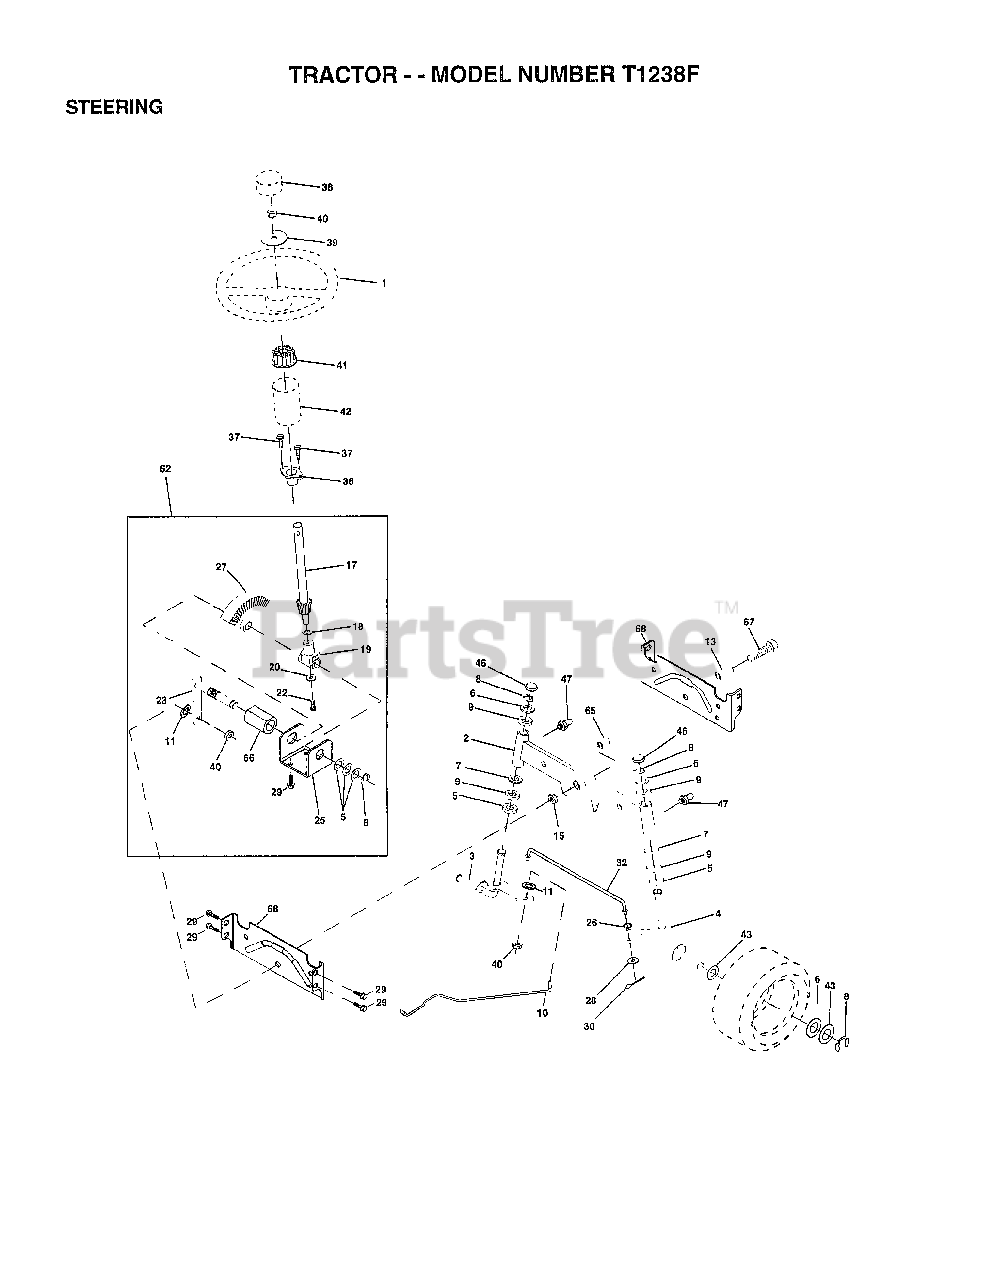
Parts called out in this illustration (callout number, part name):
2	AXLE ASM
3	SPINDLE.ASM.LH
4	"SPINDLE ASM,RH"
5	WASHER .T
6	WASHER
7	WASHER
8	RING
9	COL. SRTG. BEAR.
10	DRAGLINK-STAMPED
11	LOCKWASHER
13	BEARING AXLE
15	"NUT-LOC,FLANGE LT"
17	SHAFT ASSM STEERN
18	THRUST WASHER
19	SUPPORT.SHAFT
22	SCREW HEX SOC1/4-
25	BRKT-STEERING
26	BUSHING.DRAGLINK
27	GEAR SECTOR
28	WASHER
29	SCREW
30	COTTER PIN
32	TIE ROD
36	BUSHING.STEERING
37	"SCREW-TT,10-32 FL"
38	ST WHL INSERT CAP
39	WASHER T
40	GRIPCO NUT
41	ADAPTER-WHEEL LT
42	"TUBE, STR SHAFT"
43	WASHER
46	CAP
47	ZERK M
62	STEERING ASM KIT
65	SPACER AXLE
66	"BEARING-ARM,PITMA"
67	BOLT
68	BRACE AXLE
